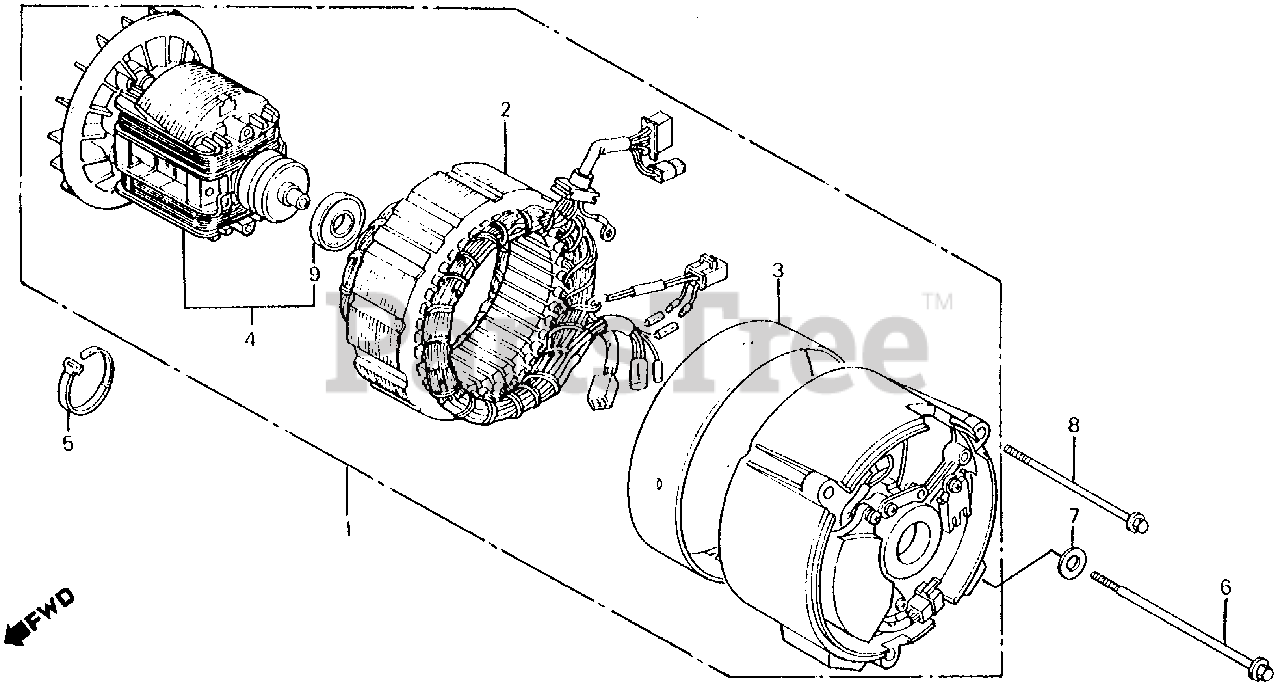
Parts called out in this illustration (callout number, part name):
1	ALTERNATOR ASSY. *NH105* (EX-A) (MAT BLACK)
2	STATOR ASSY. (EX-A)
3	COVER, STATOR *NH105* (MAT BLACK)
4	ROTOR (NOT AVAILABLE)
5	BAND, CABLE
6	BOLT, HEX. (8X154) (NOT AVAILABLE)
7	WASHER, PLAIN (8MM)
8	BOLT, FLANGE (6X125)
9	BEARING, RADIAL BALL (6002)
